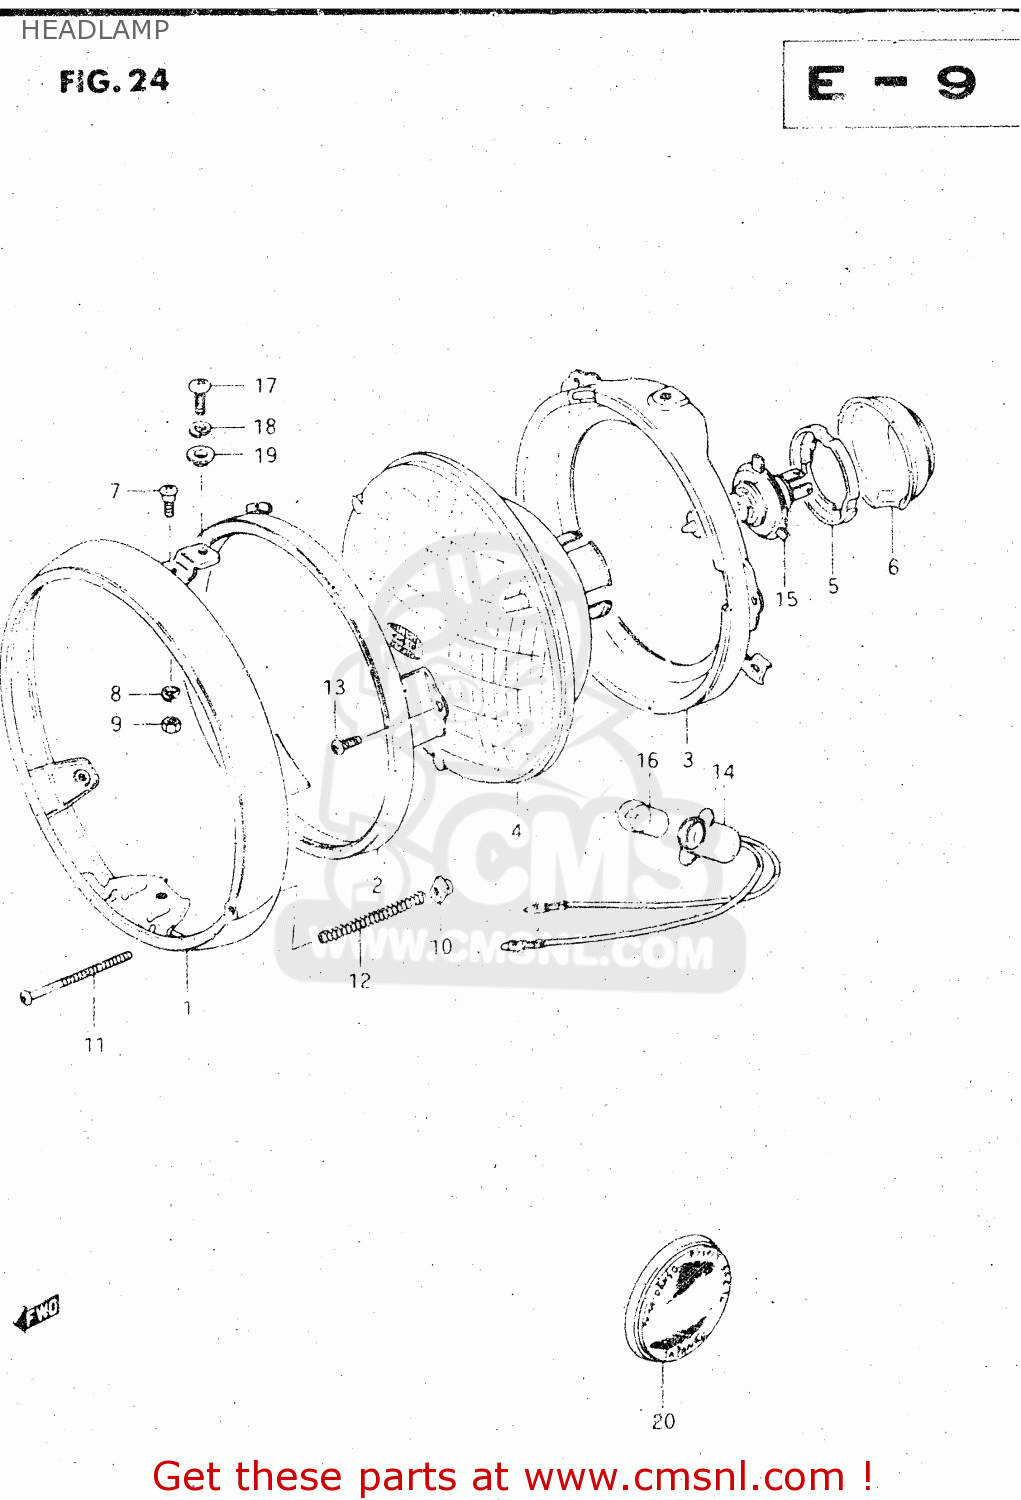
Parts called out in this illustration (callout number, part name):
1	RIM
2	RETAINING RING
3	RING
4	UNIT,HEAD LAMP
5	SETTING,BULB
6	COVER,HEADLAMP SOCKET
7	H/LAMP LENS UNIT FITING SCRE
8	LOCK WASHER
9	NUT
10	NUT
11	SCREW
12	SPRING,ADJUSTING
13	SCREW
14	SOCKET
15	BULB(12V60/55W,H4)
16	BULB(12V4W)
17	SCREW
18	WASHER,LOCK
19	WASHER
20	REFLEX REFLECTOR,RR
